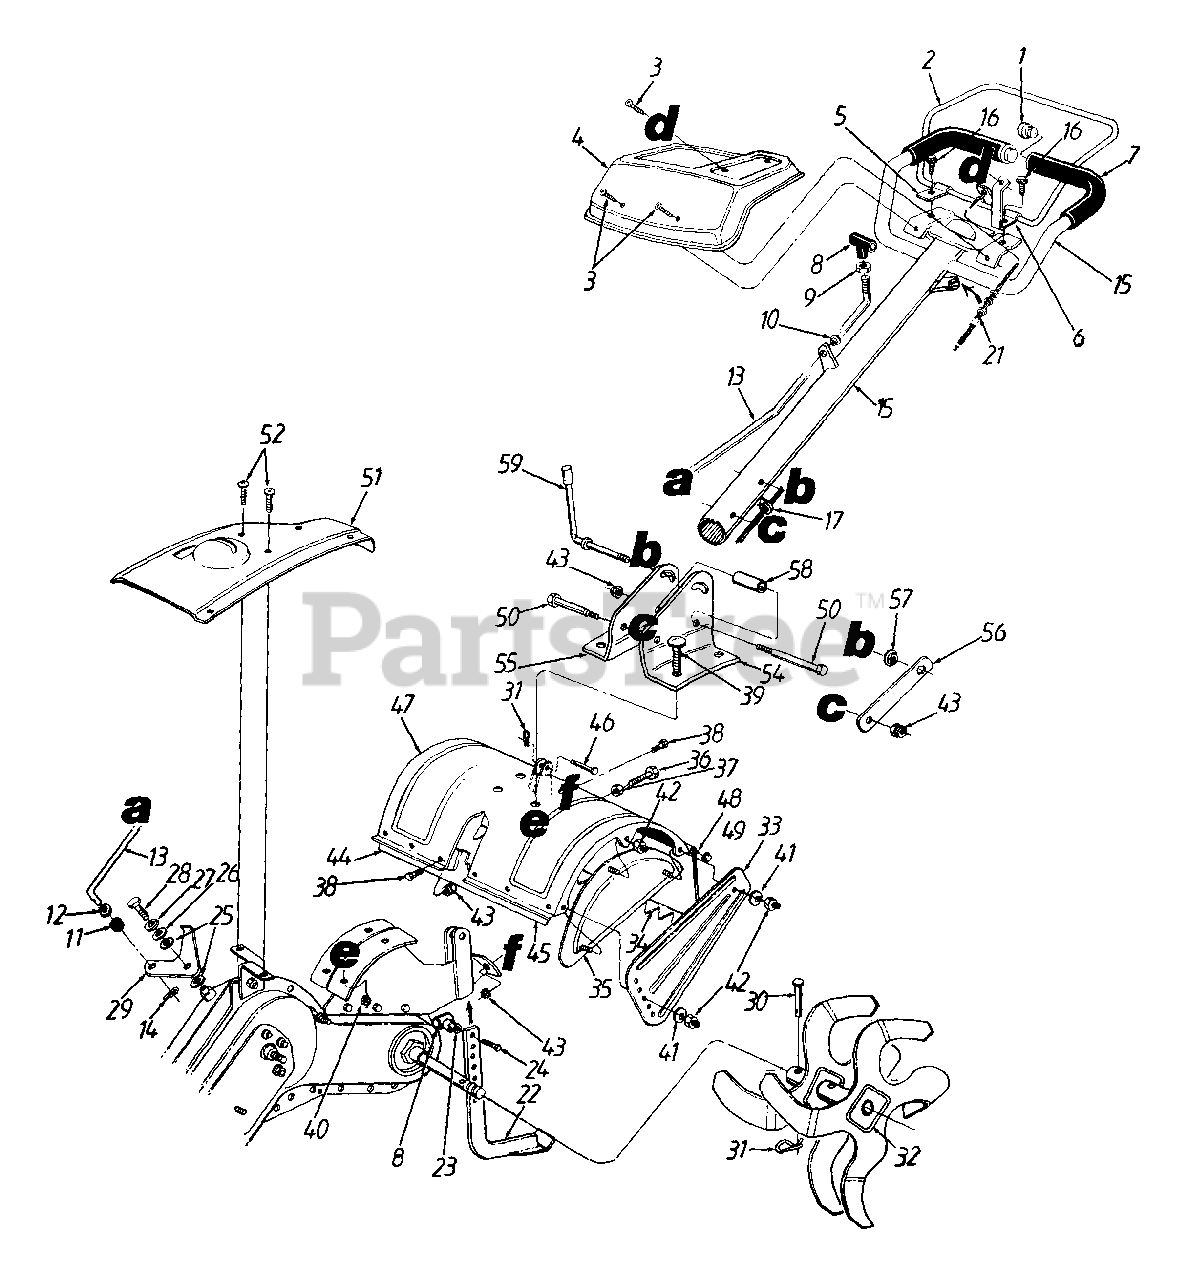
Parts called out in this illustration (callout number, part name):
1	Vinyl End Plug
3	Torx Mach. AB-Tap Scr. 1/4 x .62" Lg.
7	Grip
9	Hex Jam Nut 3/8-16 Thd.
10	Bushing 3/8" I.D.
11	Rubber Washer
12	Fl-Wash. .344" I.D. x .6" O.D.
13	Gear Shift Rod
14	Hairpin Clip
21	Clutch Cable
23	Fl-Wash. 3/8" I.D. x 5/8" O.D.
24	Hex Bolt 3/8-16 x .75" Lg.
25	Washer 1" O.D. (Hdn.)
26	Fl-Wash. .281" I.D. x .73" O.D.
27	L-Wash. 1/4" I.D.
28	Hex Bolt 1/4-20 x .62" Lg. (Gr. 5)
36	Hex Cap Bolt 5/16-18 x 1.25" Lg.
37	Hex Nut 5/16-18 Thd.
38	Hex Bolt 5/16-18 x .75" Lg.
39	Carriage Bolt 3/8-16 x 1" Lg.
40	Hex Ins. L-Nut 3/8-16 Thd.
41	Bell-Wash. .345" I.D. x .88" O.D.
42	Hex Cap L-Nut 5/16-18 Thd.
43	Hex Flange Top L-Nut 5/16-18 Thd.
46	Clevis Pin .375" Dia.
49	Cap Speed Nut
50	Hex Bolt 5/16-18 x 3" Lg.
52	Torx Mach. AB-Tap Scr. 1/4 x .6"
57	Hex Flange Nut 3/8-24 Thd.
58	Spacer .322 Dia.
59	Handle Adjustment Crank
